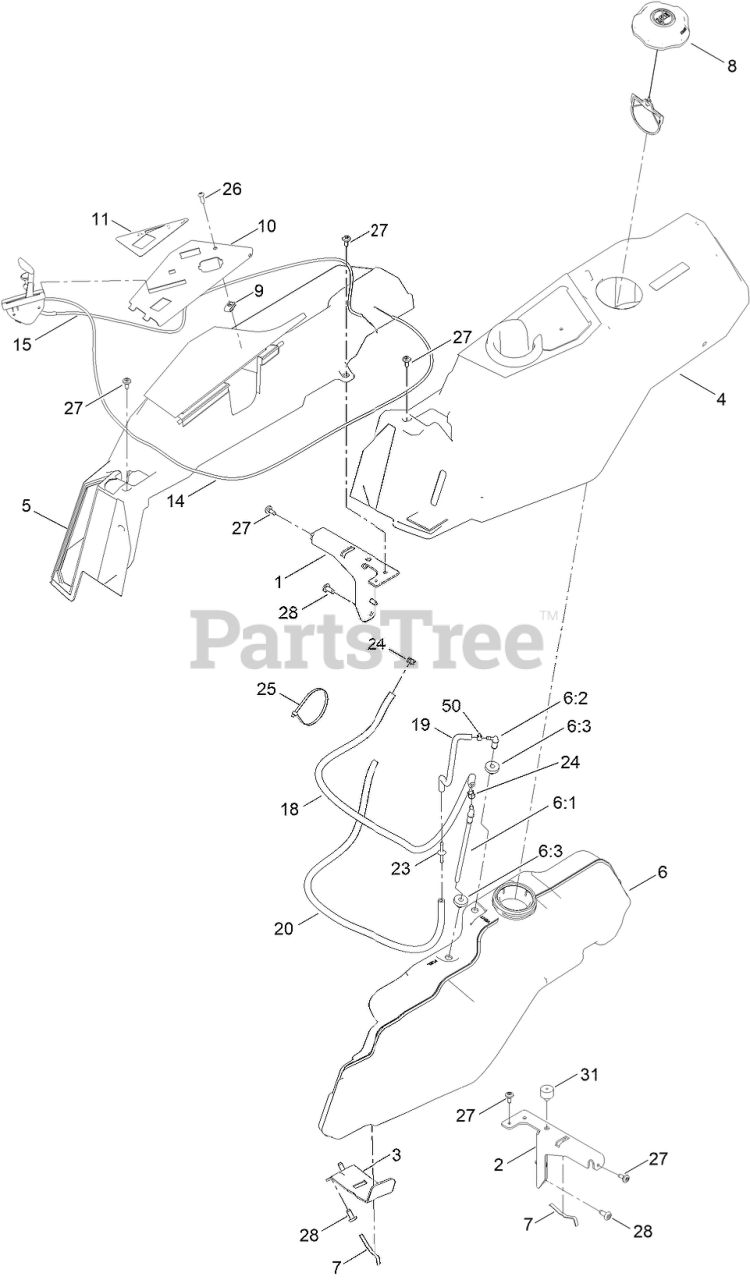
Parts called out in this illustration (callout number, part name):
1	SUPPORT-POD, RH
2	SUPPORT-POD, LH
3	SUPPORT-TANK, FUEL
4	POD-LH
5	POD-RH
6	TANK-FUEL ASM
6:1	CONNECTOR-ELBOW, 90 DEG
6:2	FITTING-ELBOW 90
6:3	BUSHING
7	SPRING
8	CAP-FUEL, RATCHETING
10	PANEL - CONTROL
11	DECAL-PANEL CONTROL
14	CABLE-THROTTLE
15	CABLE-CHOKE
18	HOSE-FUEL
19	HOSE-FUEL
20	HOSE, FUEL
23	ADAPTER ORIFICE
24	CLAMP-HOSE
25	TIE-CABLE
26	SCREW-PRH
27	SCREW-SHOULDER
31	BUMPER-GROMMET
50	CLAMP-HOSE
